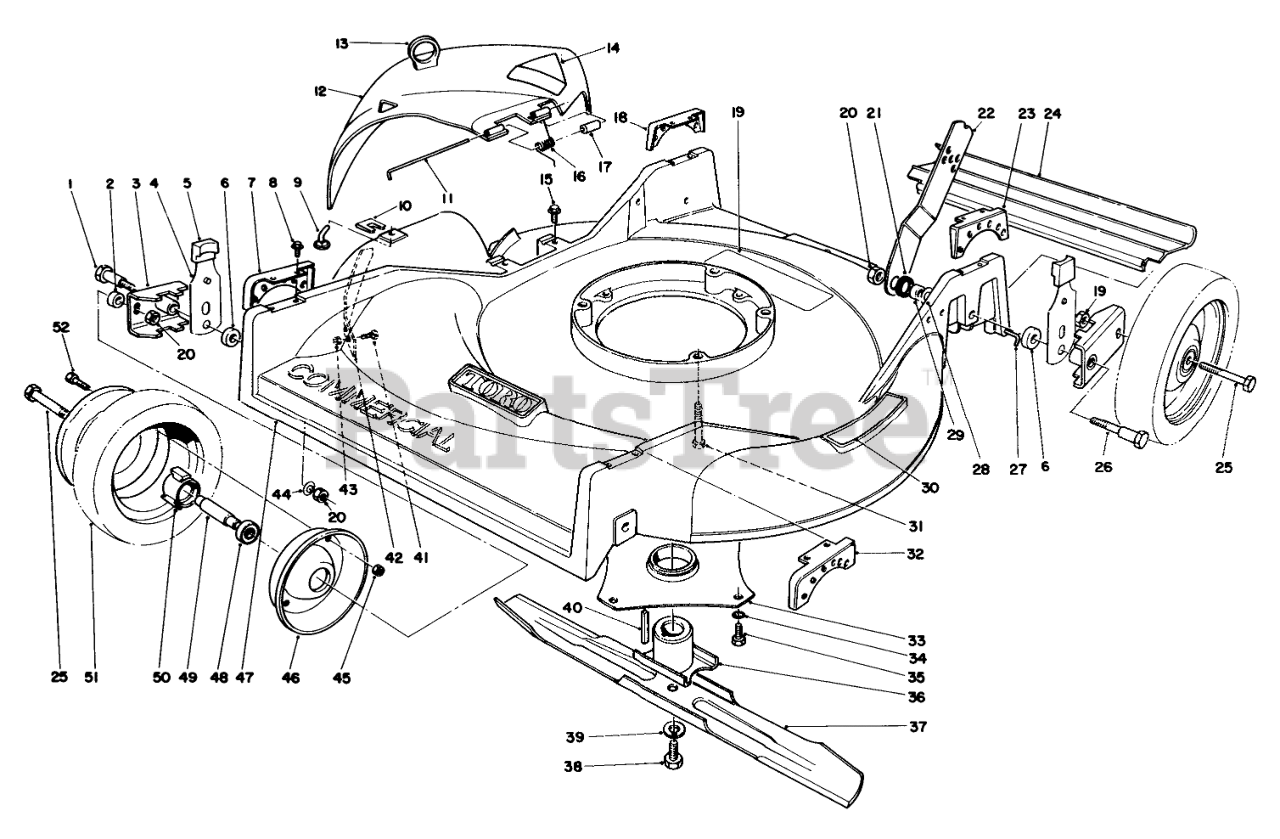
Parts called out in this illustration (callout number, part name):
1	PIVOT SCREW
2	SPACER-WHEEL
3	PIVOT ARM
4	SPRING ARM ASM-FRONT
5	KNOB-ARM
6	SPACER-PIVOT
7	FRT RIGHT QUAD
8	SCREW-HWHTF
9	BAG CHUTE PIN
10	BAG CHUTE CLIP PIN
11	DEFLECTOR HINGE PIN
12	Deflector (Incl. Ref. #14)
13	LIFT LOOP
14	DECAL-DANGER
15	SCREW-HWH
16	DEFLECTOR SPRING
17	SLEEVE
18	REAR RIGHT QUAD
19	DECAL-INSTRUCTION, SAFETY
20	NUT-LOCK, NI
21	HANDLE LATCH SPACER
22	Latch-Handle
23	REAR LEFT QUAD
24	SHIELD - TRAILING
25	SCREW-HH
26	REAR PIVOT SCREW
27	SHIELD ROD
28	WASHER-BELLEVILLE
29	HANDLE LATCH SPACER
30	STEP PAD DECAL
31	Screw-Flange Head
32	FRT LEFT QUAD
33	CRNKSHFT PROTECT ASM
34	WASHER-LOCK, INTERNAL
35	SCREW-HWHTF
36	RETAINER-BLADE
37	Blade
38	SCREW-HH
39	WASHER-LOCK
40	KEY-SQUARE
41	SCREW-CARR
42	Bar-Safety
43	NUT-LOCK, NI
44	WASHER-BELLEVILLE
45	NUT-LOCK, NI
46	Wheel-Half
47	Housing (Incl. Ref. #19 & 30)
48	BEARING-WHEEL
49	SPACER-BEARING
50	HUB-BEARING
52	SCREW-HH
